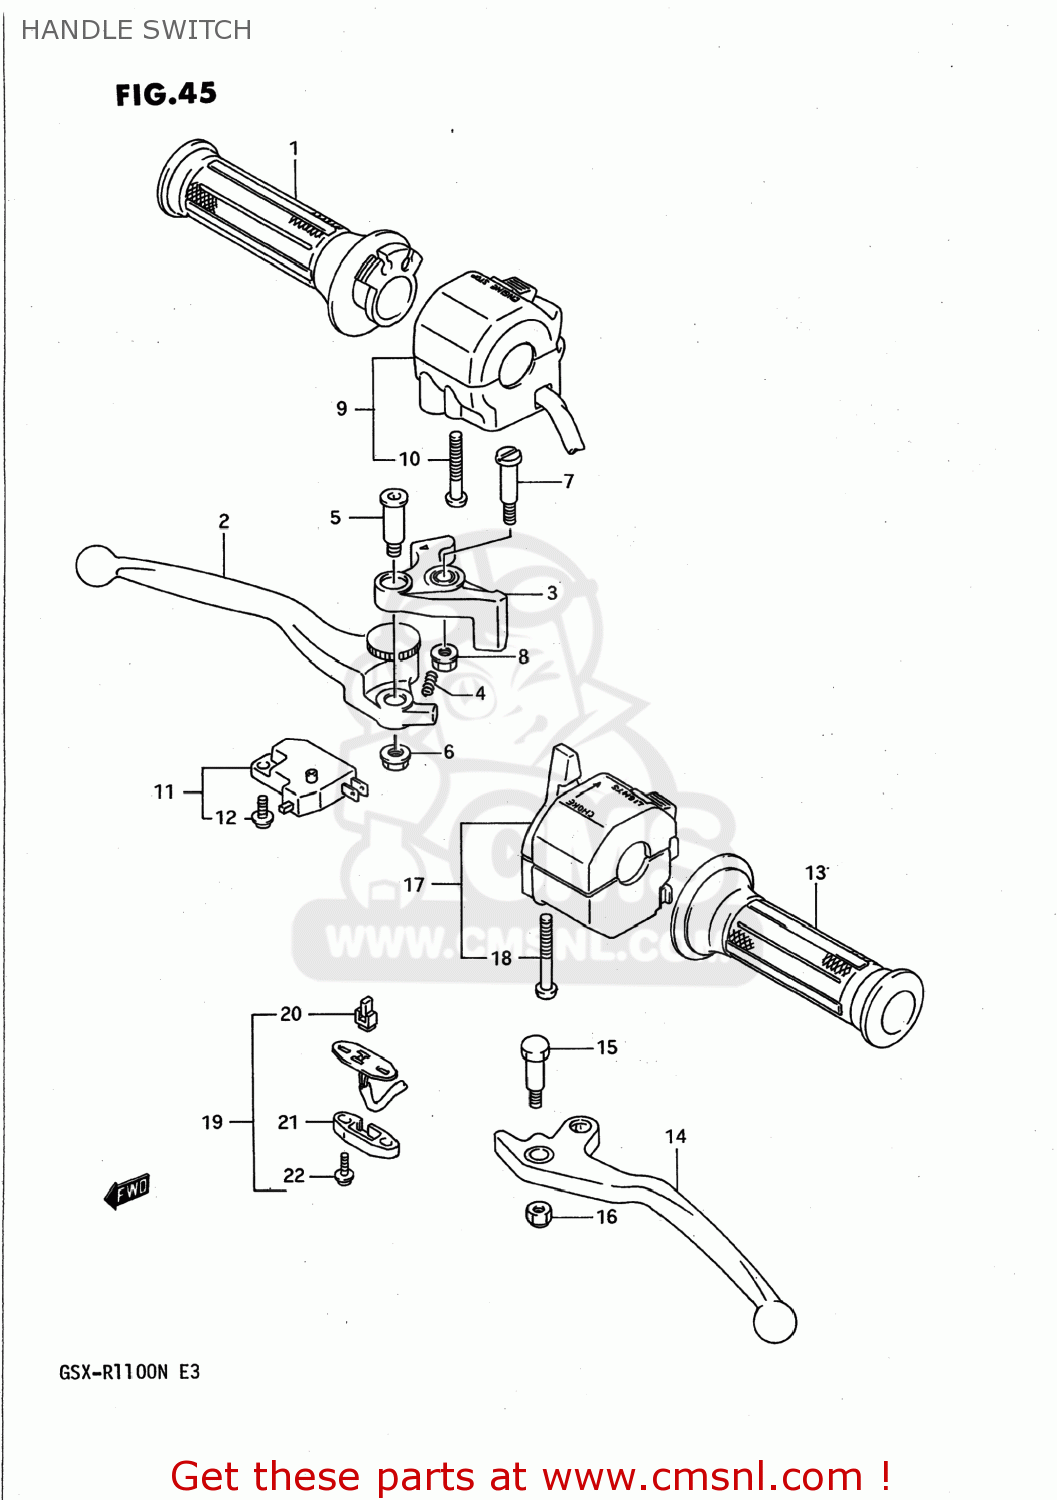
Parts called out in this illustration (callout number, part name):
1	GRIP,THROTTLE
2	LEVER,ADJUST
3	KNOCKER
4	SPRING
5	BOLT,LEVER
6	NUT
7	BOLT,LEVER PIVOT
8	NUT 6MM
9	SWITCH ASSEMBLY,HANDLE,RIGHT
10	SCREW, 5X45
11	SWITCH ASSEMBLY,STOP
12	SCREW
13	GRIP,L
14	LEVER,CLUTCH (SILVER)
15	BOLT,LEVER
16	NUT
17	SWITCH ASSEMBLY,HANDLE,LEFT
18	SCREW, 5X45
19	SWITCH ASSEMBLY,CLUTCH
20	CONTACT,SWITCH
21	COVER,FR BK TERMINAL BASE
22	SCREW
